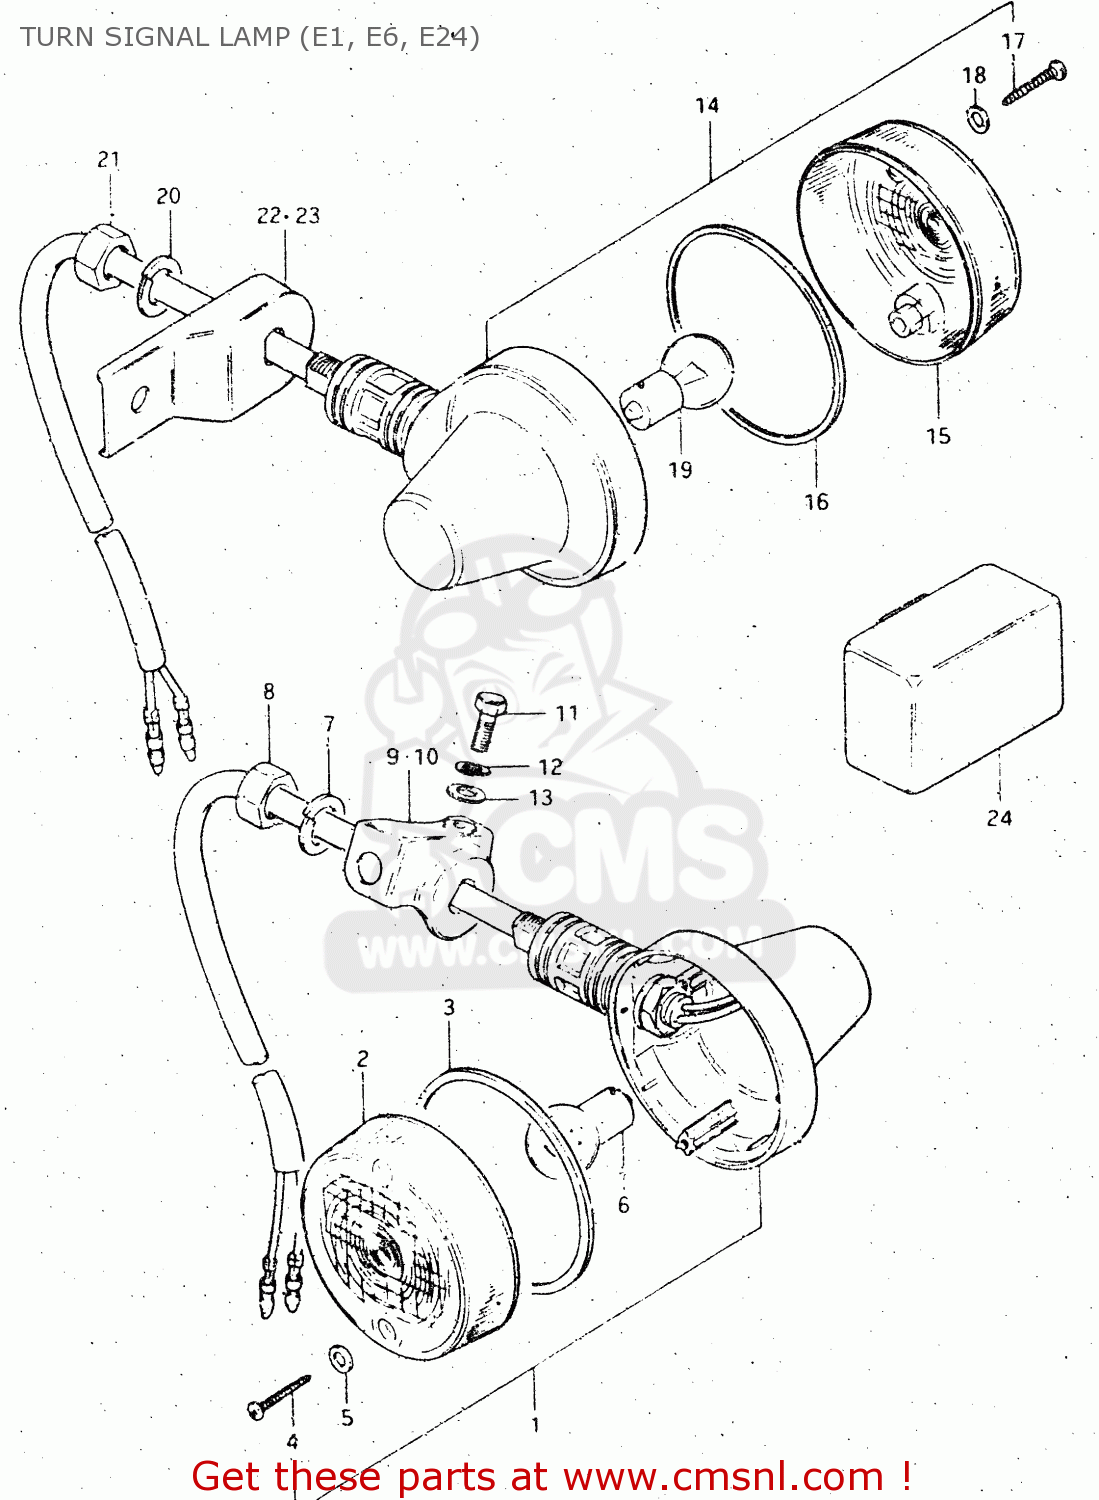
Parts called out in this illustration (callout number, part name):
1	LAMP ASSEMBLY,FRONT TURN SIGNAL
2	LENS
3	GASKET (NAS)
4	SCREW TAPP.
5	GASKET (NAS)
6	BULB(6V17W,STANLEY,A4513A)
7	WASHER
8	NUT 12MM
9	BRACKET,TURN SIGNAL LAMP
10	BRACKET,TURN SIGNAL LAMP
11	BOLT
12	LOCK WASHER
13	WASHER
14	LAMP ASSY,RR TURNSIGNAL
15	LENS
16	GASKET (NAS)
17	SCREW TAPP.
18	GASKET (NAS)
19	BULB(6V17W,STANLEY,A4513A)
20	WASHER
21	NUT 12MM
22	BRACKET,REAR TURN SIGNAL
23	BRACKET,REAR TURN SIGNAL
24	RELAY,TURN SIGNAL
